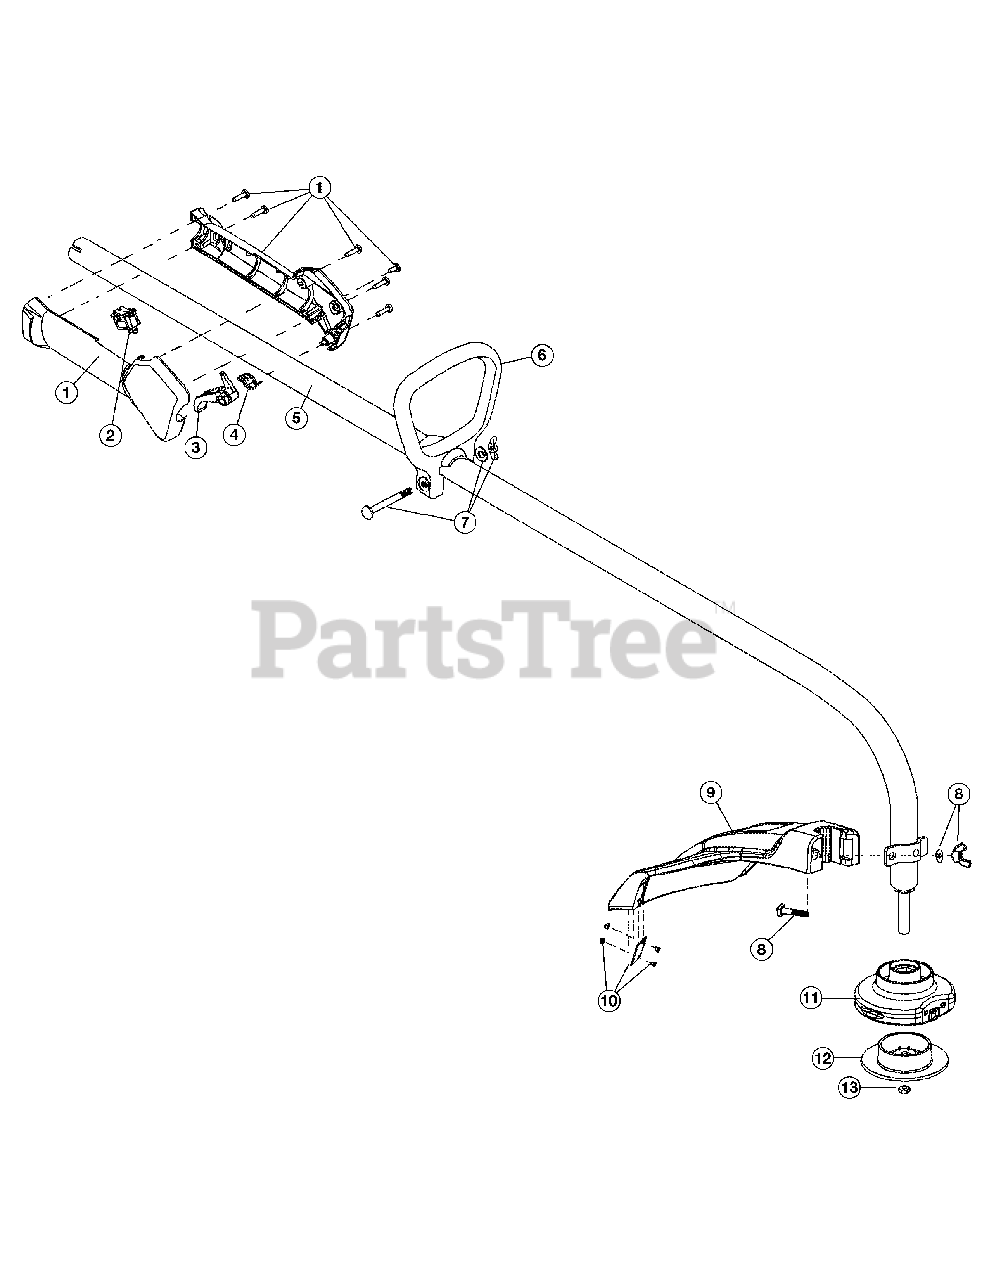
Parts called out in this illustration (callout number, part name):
1	Throttle Housing Assembly
3	Throttle Trigger
4	Throttle Trigger Spring
5	Drive Shaft Housing Assembly
6	D-Handle
7	Handle Hardware
8	Guard Mounting Hardware
9	Guard
10	Blade Assembly
11	Fixed Line Head Assembly
12	Glide Cap
13	Locknut
